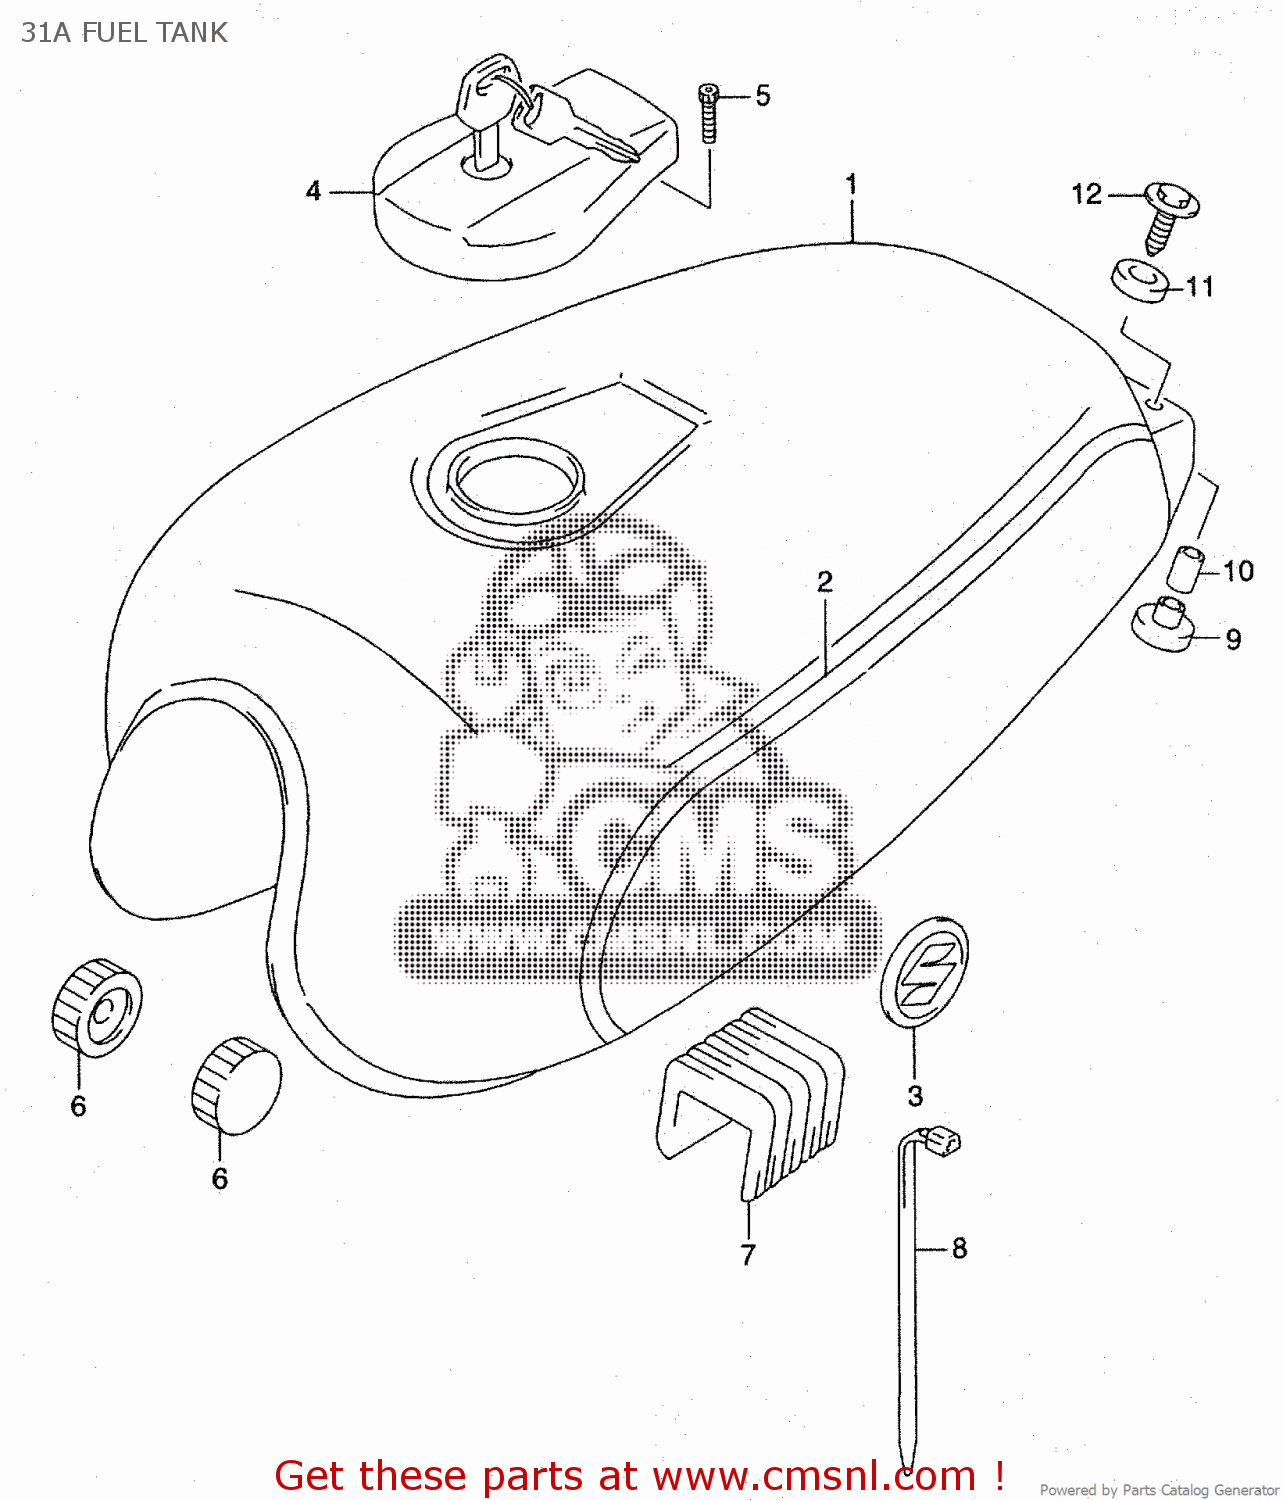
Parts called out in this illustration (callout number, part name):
5	BOLT
6	CUSHION
7	CUSHION
8	CLAMP(L:250)
9	CUSHION
10	SPACER(6.5X9X18)
11	CUSHION,FUEL TANK RR
12	BOLT(6X30)
